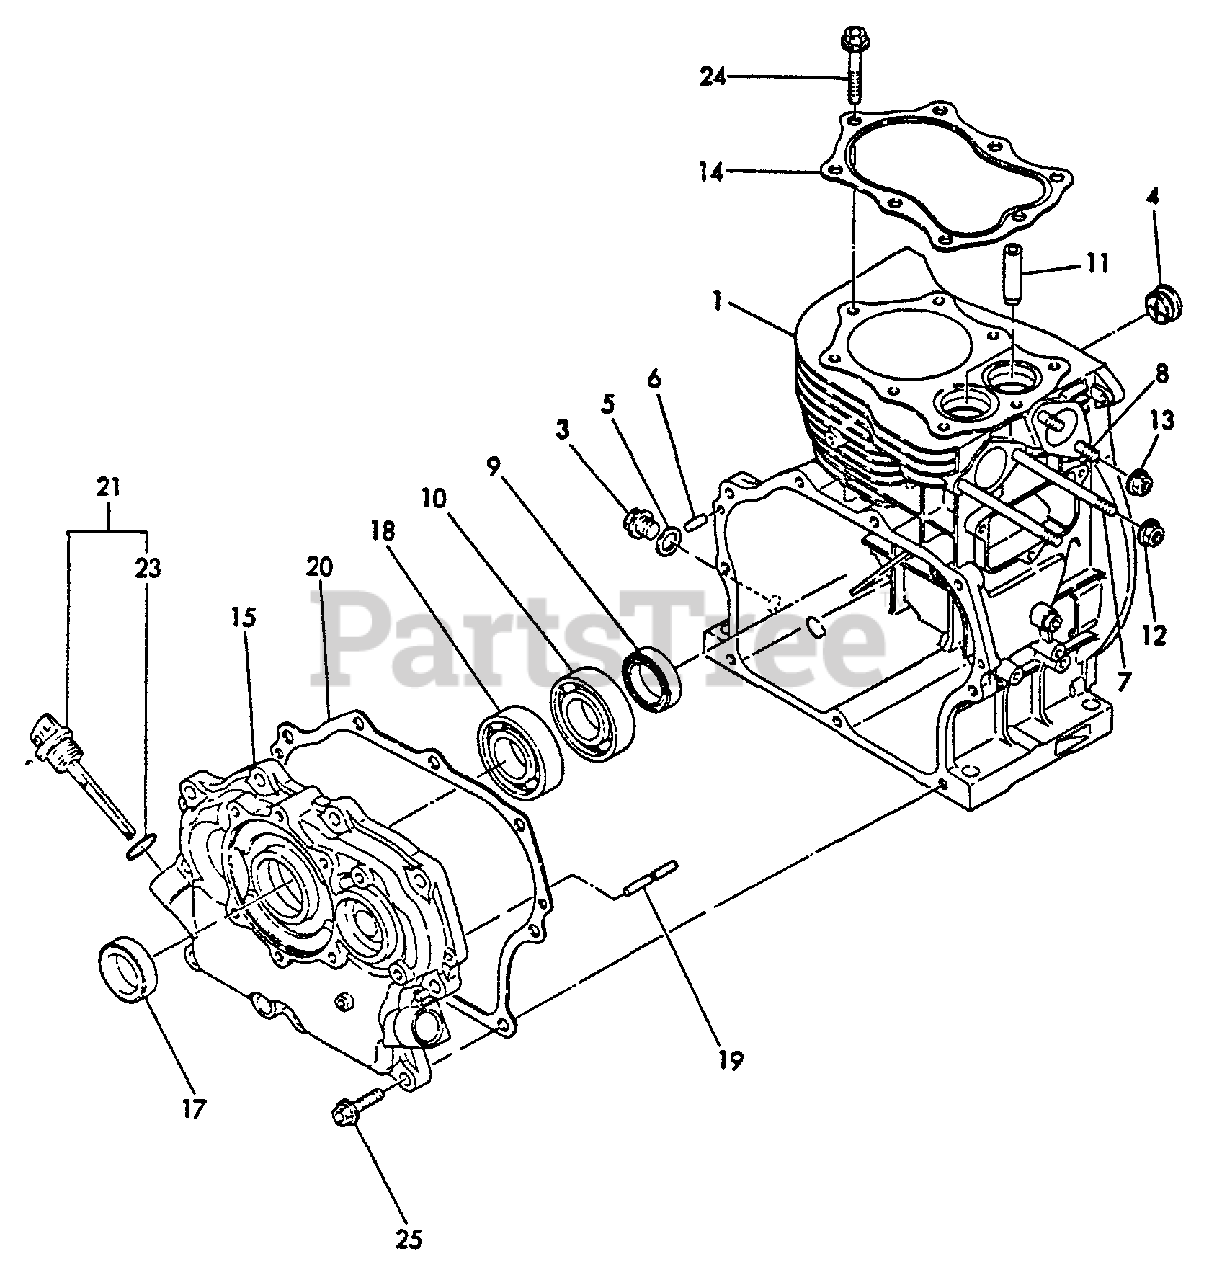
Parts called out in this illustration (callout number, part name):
1	CYLINDER BODY ASSY
3	PLUG, DRAIN
4	PLUG
5	GASKET
6	PARALLEL PIN 6×16
7	STUD M8×95 PLATED
8	STUD -- PLATED
9	SEAL, OIL
10	BEARING, BALL 6206C4
11	GUIDE, VALVE
12	U-NUT M8
13	U-NUT M8
14	GASKET, CYLINDER
15	COVER, CRANKCASE
17	SEAL, OIL
18	BEARING, BALL 6206C4
19	SHAFT, GOVERNOR
20	GASKET, CRANKCASE
21	CAP ASSY
23	O-RING 1A P-18.0
24	BOLT - 8×50
25	BOLT - 8×30 -- PLATED
